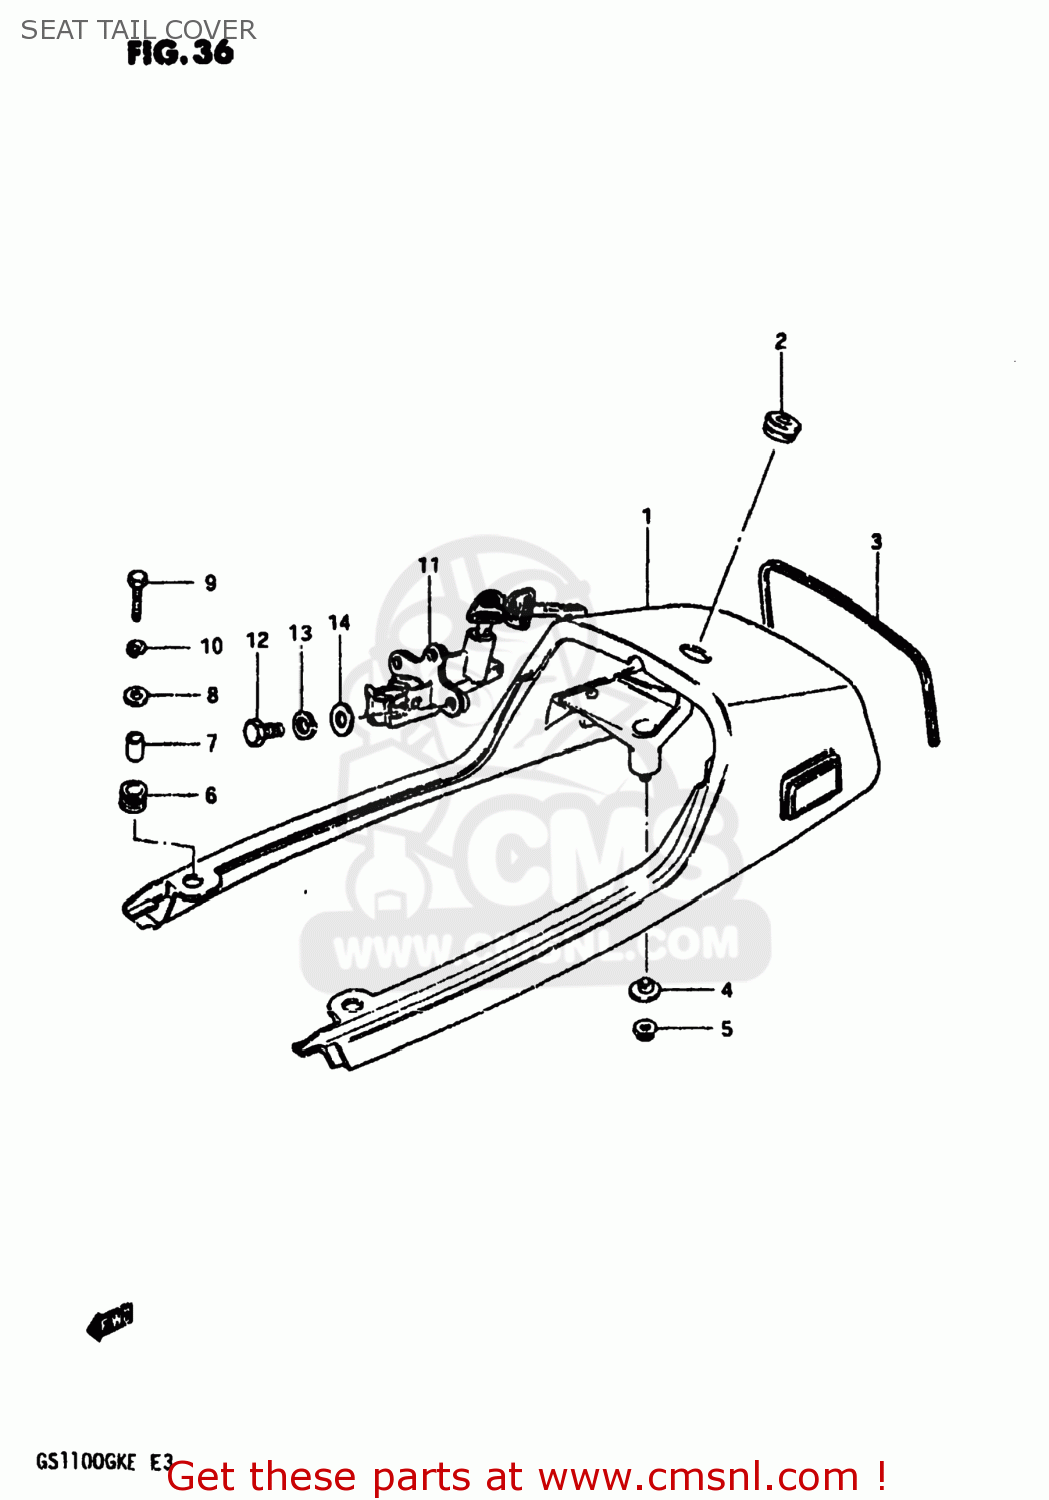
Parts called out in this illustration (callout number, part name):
1	COVER SET,SEAT TAIL
2	GROMMET,SEAT LOCK HOLE
3	MOLDING,SEAT TAIL COVER
4	WASHER
5	NUT 6MM
6	CUSHION
7	SPACER (7X10X12)
8	WASHER (6.5X24X1.6)
9	BOLT
10	LOCK WASHER
11	LOCK SET,SEAT
12	BOLT
13	LOCK WASHER
14	WASHER
